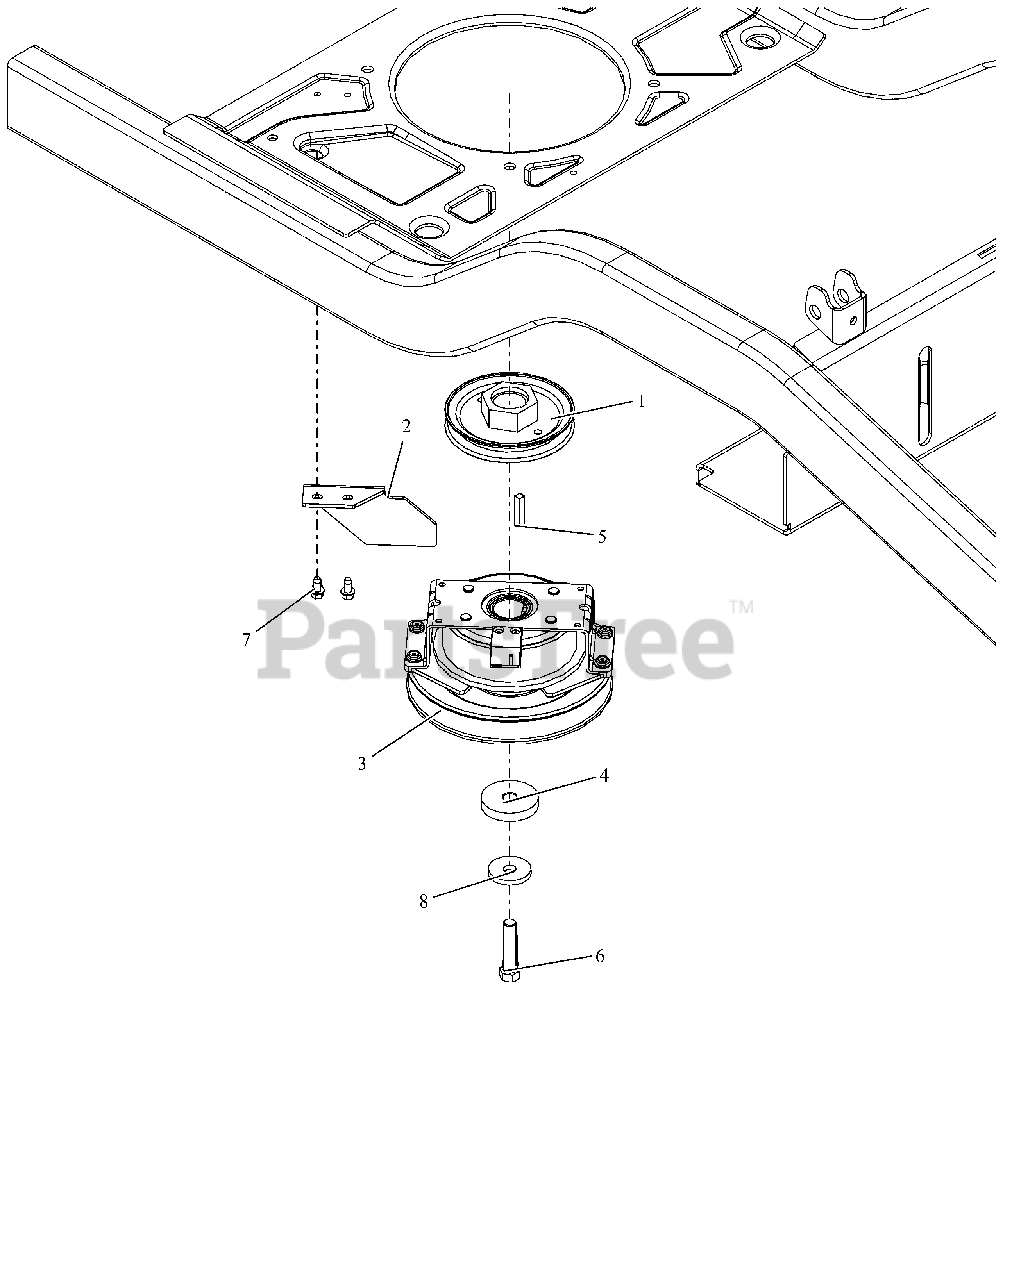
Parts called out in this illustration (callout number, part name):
1	WLDMT,PULLEY-4.50ODX1.127
2	BRKT, CLUTCH STOP HD
3	CLUTCH, OGURA DBLS SPRG 1.13"
4	SPACER, .474/.459X2.00X.350
5	KEY-SQ .25 X 1.25 X .25 SAE
6	BLT, HEX 0.4375-20X2 G8 ZCC NT
7	SCR-TAP .25-20X.50 HWH ZCC
8	WASHER, 7/16" SPRING DISK
